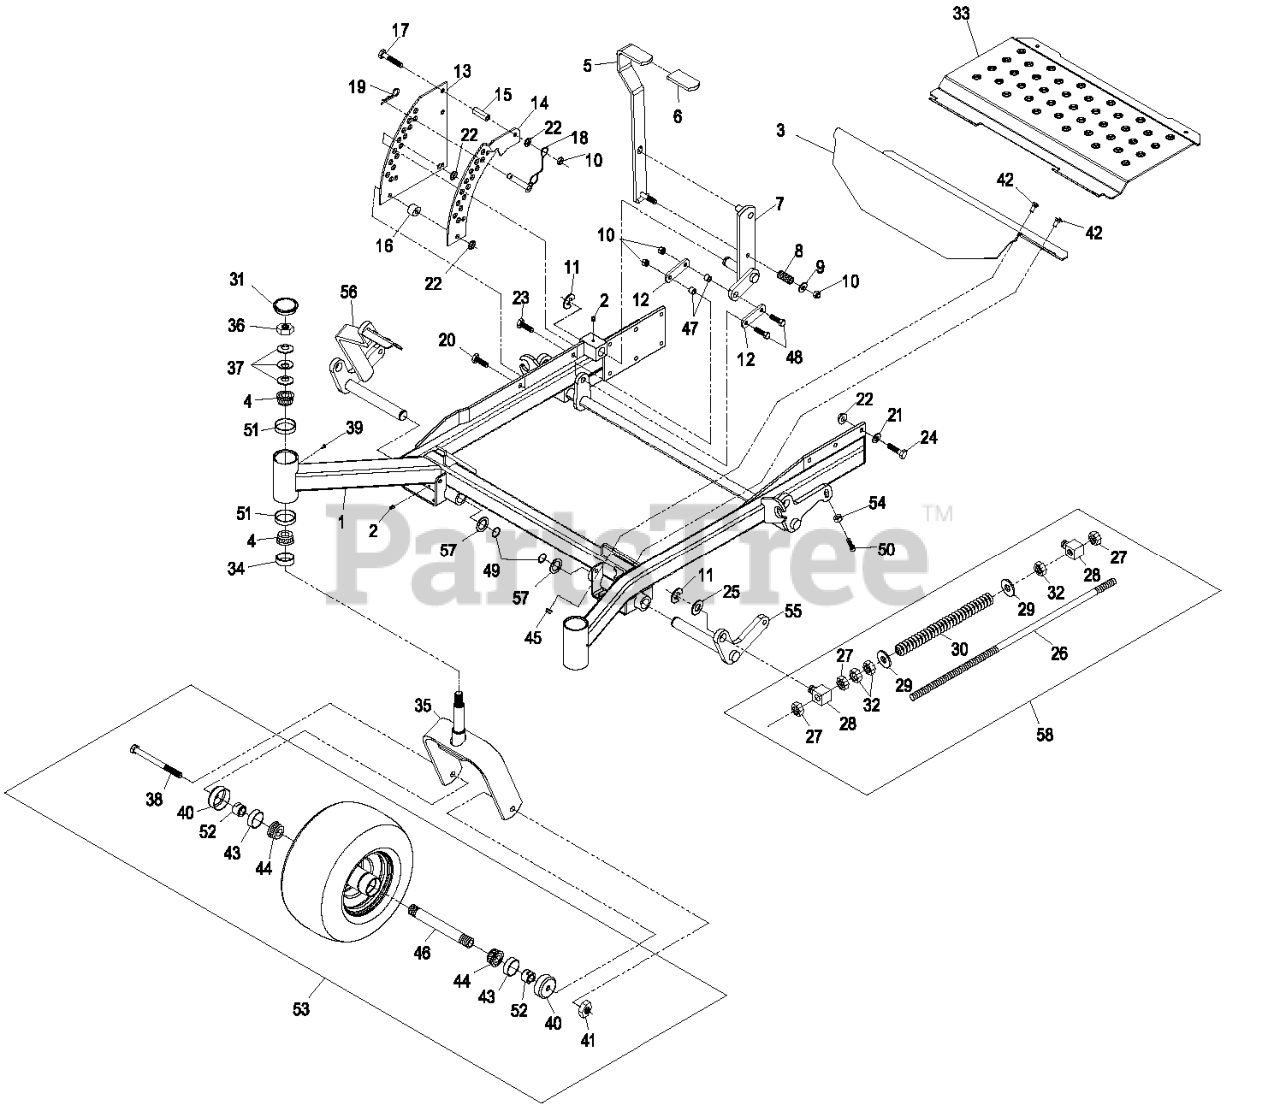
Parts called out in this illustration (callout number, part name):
1	ASM, FRONT FRAME 60"
2	FITTING-GREASE
3	ASM, FLOORPAN FRONT W/DEC
4	Cone-Bearing Tapered Roller
5	LIFT LEVER/GRIP ASM
6	GRIP-LEVER, LIFT
8	SPRING-COMPRESSION
9	WASHER-FLAT
10	NUT-LOCK, NI
11	RING-RETAINING, EXT
12	ARM-LIFT, DECK
13	PLATE-LIFT, DECK
14	PLATE-LIFT,DECK W/DECAL L
15	BUSHING-LEVER, LIFT
16	Stop, Deck Height
17	SCREW-HH
18	PIN-HITCH (W/LANYARD)
19	PIN-COTTER
20	SCREW-HH
21	WASHER-BELLEVILLE
22	NUT-HHF, WHIZ
23	SCREW-HH
24	SCREW-HH
25	WASHER-FLAT
26	ROD-LIFT, DECK
27	NUT-HEX
28	SWIVEL-DECK MOUNT, REAR
29	WASHER-FLAT
30	SPRING,DECK SUPPORT
31	CAP-GREASE
32	NUT-JAM
33	ASM, FLOORPAN LIFTOUT W/D
34	SEAL-GREASE
36	NUT-LOCK, NI
37	WASHER-BELLVILLE
38	SCREW-HH
40	GUARD-SEAL
41	NUT-LOCK, NI
42	BOLT-CARR
43	SEAL-CASTER
44	BEARING-CONE, TAPERED ROLLER
47	BUSHING
48	SCREW-HH
49	RING-RETAINING
50	SCREW-HSH
51	CUP-BEARING
52	SPACER-NUT
54	NUT-JAM
55	WLD,FRONT LIFT SHAFT-LH
56	WLD,FRONT LIFT W/LEVER
57	WASHER-SPACER
58	ASM,FRONT FRAME SPRING
